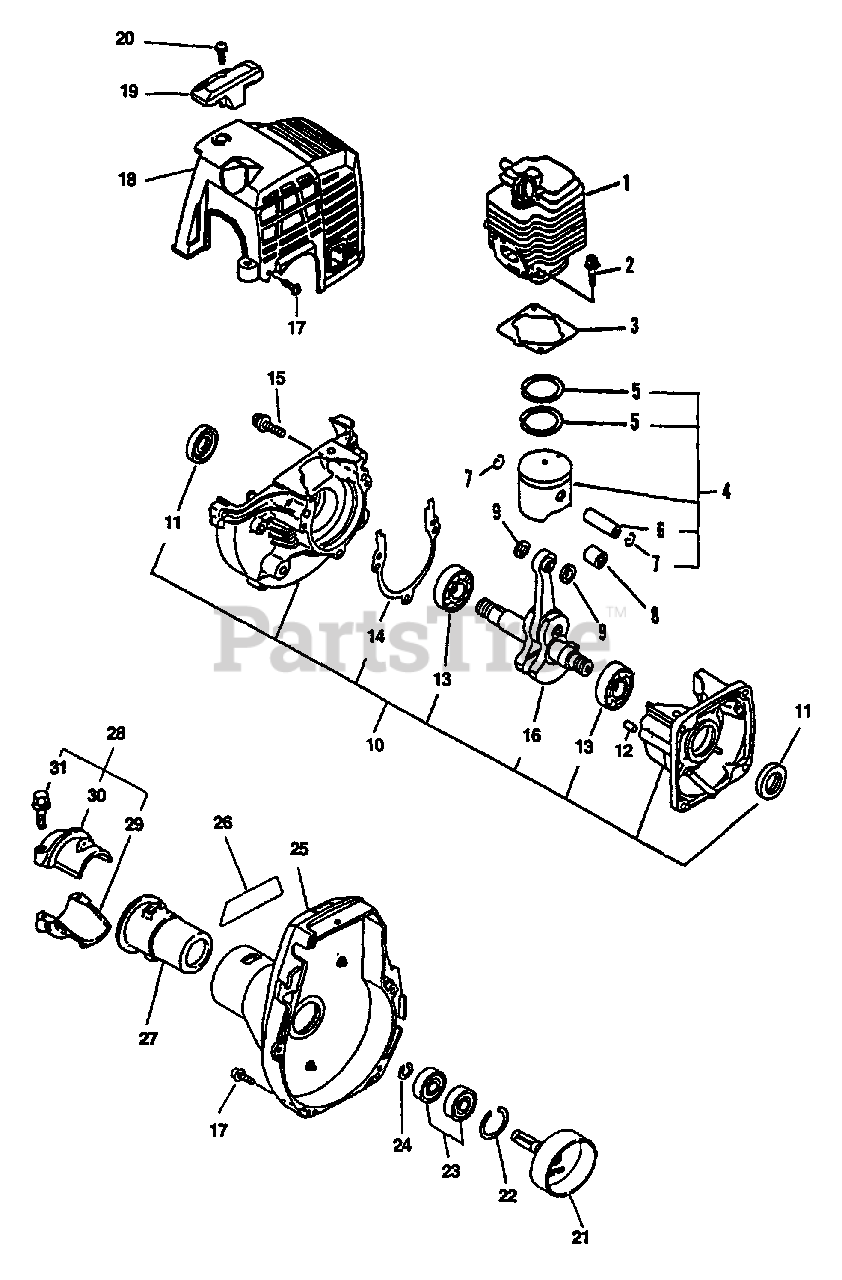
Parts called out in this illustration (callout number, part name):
1	CYLINDER
2	SCREW - 5X22
3	GASKET, CYLINDER
4	PISTON KIT
5	RING, PISTON
6	PIN, PISTON
7	RING, RETAINING
8	BEARING, NEEDLE
9	SPACER, PISTON
10	CRANKCASE KIT
11	SEAL, OIL
12	PIN - LOCATING
13	BEARING, BALL - 6201
14	GASKET, CRANKCASE
15	SCREW - 5X28
16	CRANKSHAFT ASSY
17	SCREW - 4X16
18	COVER, ENGINE
19	GUARD - TOP
20	SCREW - 5X16
21	DRUM, CLUTCH
22	RING, RETAINING - 28
23	BEARING, BALL - 6001
24	RING, RETAINING - 12
25	CASE, FAN
26	LABEL - MODEL GT-2400
27	CUSHION
28	HOLDER KIT
29	CLAMP, MAIN PIPE - LOWER
30	CLAMP, MAIN PIPE - UPPER
31	BOLT - 5X25
